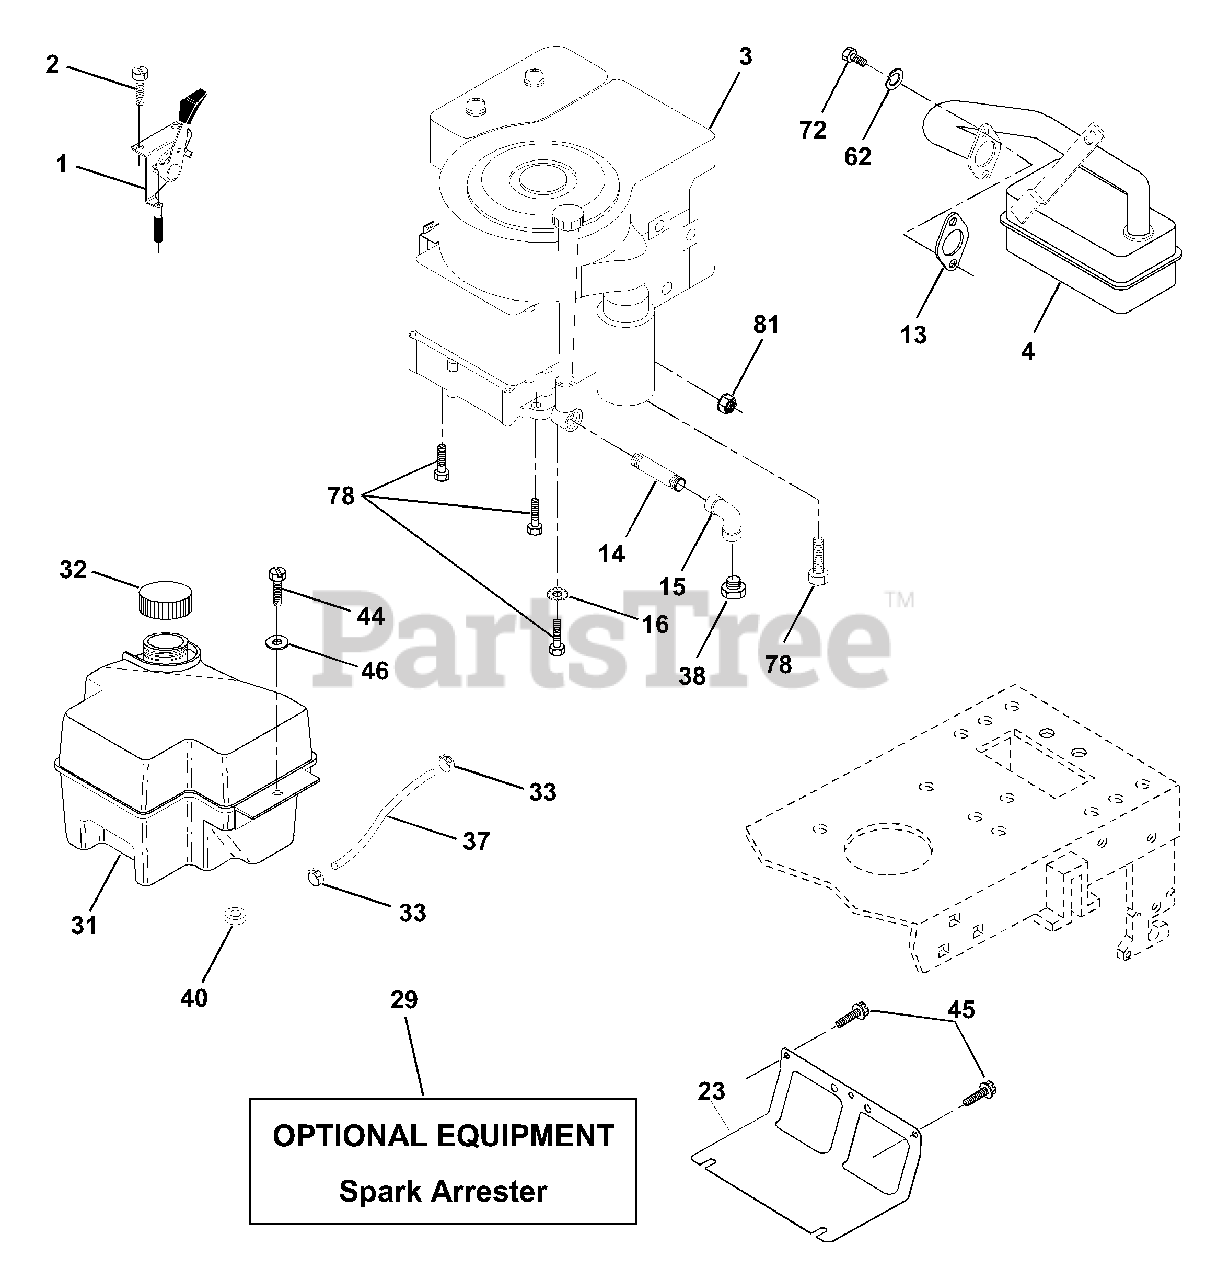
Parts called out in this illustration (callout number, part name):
1	Control Th/ch Flag
2	Screw Hex Thd Cut 1/4-20x5/8 T
4	Muffler Exhaust
13	Gasket Muffler
14	Nipple Pipe 4-12"
15	Elbow Std 90 Degree 3/8-18 Npt
16	Washer Lock Ext Tooth 3/8
23	Shield Brn/Dbr Guard
29	Arrestor Spark
31	Tank Fuel Front 2 00
32	Cap Fuel
33	Clamp Hose Black
37	Line Fuel 20"
38	Plug Oil Drain
40	Bushing Snap Nyl Blk Fuel Line
44	Screw Hex wsh Thdrol 1/4-20x3/4
45	Screw Hex Wsh Thdrol 3/8-16 x 3/4
46	Washer 9/32 X 7/8 X 16 Ga
62	Washer Lock Hvy Hlcl Spr 5/16
72	Screw Hex Hd Cap 5/16-18 x 3/4
78	Screw 3/8-16 x 1-1/4
81	Nut Keps Hex 1/4-20 Unc
